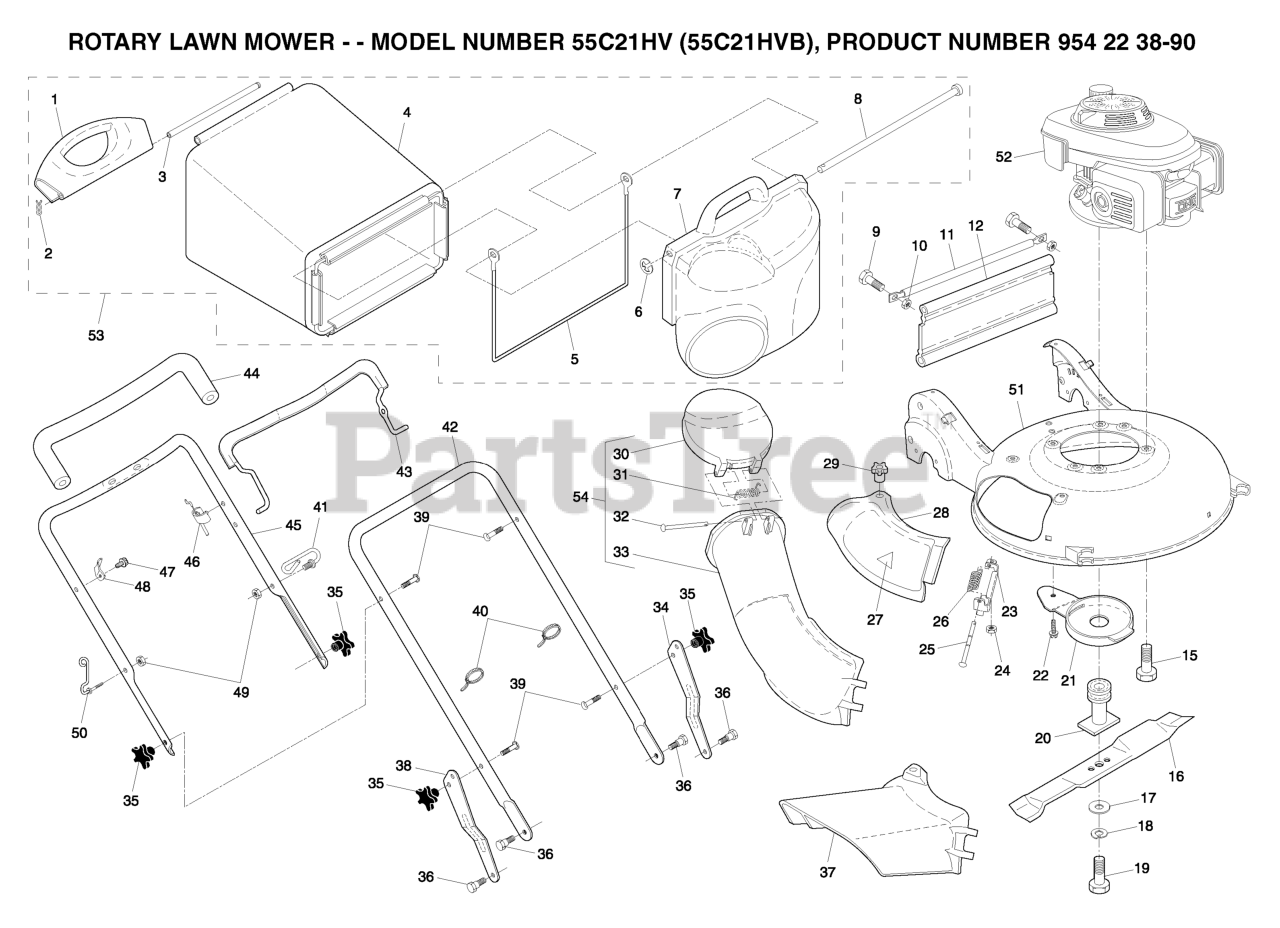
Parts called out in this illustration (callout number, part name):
1	HANDLE.GRASSBAG.REAR.H-GRAY
2	COTTER PIN (3 2)(2 2MC)
3	ROD.REAR.HANDLE.YELLOW
4	GRASSBAG
5	FRAME, GRASSBAG
7	DOOR, GRASSBAG
8	ROD, PIVOT
10	LOCKNUT.NYLOC.1/4-20
11	TUBE, REAR SKIRT
12	SKIRT, REAR
15	BOLT 3/8-16X1-1/8
16	21" MULCH BLADE PREMIUM
17	WASHER,HARDEN
18	LOCKWASHER
19	SCREW.HX.HEAD.3/8-24
21	DEBRIS SHEILD
22	SCREW 1/4X20
23	BRACKET.ASM.HINGE
24	LOCK NUT
25	ROD.HINGE.1/4"3.82"
26	SPRING.MULCH.DOOR
27	DECAL HYT
28	MULCHER DOOR
29	KNOB.MULCH.DOOR
30	CHUTE.DOOR.21.HV.H-GRAY
32	ROD.HINGE.1/4"3.82"
33	DISCHARGE CHUTE PLASTIC
34	ADJUSTMENT BRACKET, LOWER LH
35	KNOB.HANDLE.STAR.HUSQ.GRAY
36	SHOULDER BOLT
37	GUARD.CLIP.ON.21.HV.GRAY
38	BRACKET.ADJ.LOWER.HDL.RT.GREY
39	HANDLE BOLT
40	TIE GUIDE
42	HANDLE.LOWER.GREY
43	BAIL CONTROL
44	GRIP.HANDLE.FOAM.WIDE.(1 SIDE)
45	HANDLE.ASM.UPPER.W/GRIP
46	ASSY ZONE CONTROL
48	BRACKET
50	GUIDE.ROPE.WALK.MOWER
54	CHUTE.LOWER.ASM.WALK.MOWER
